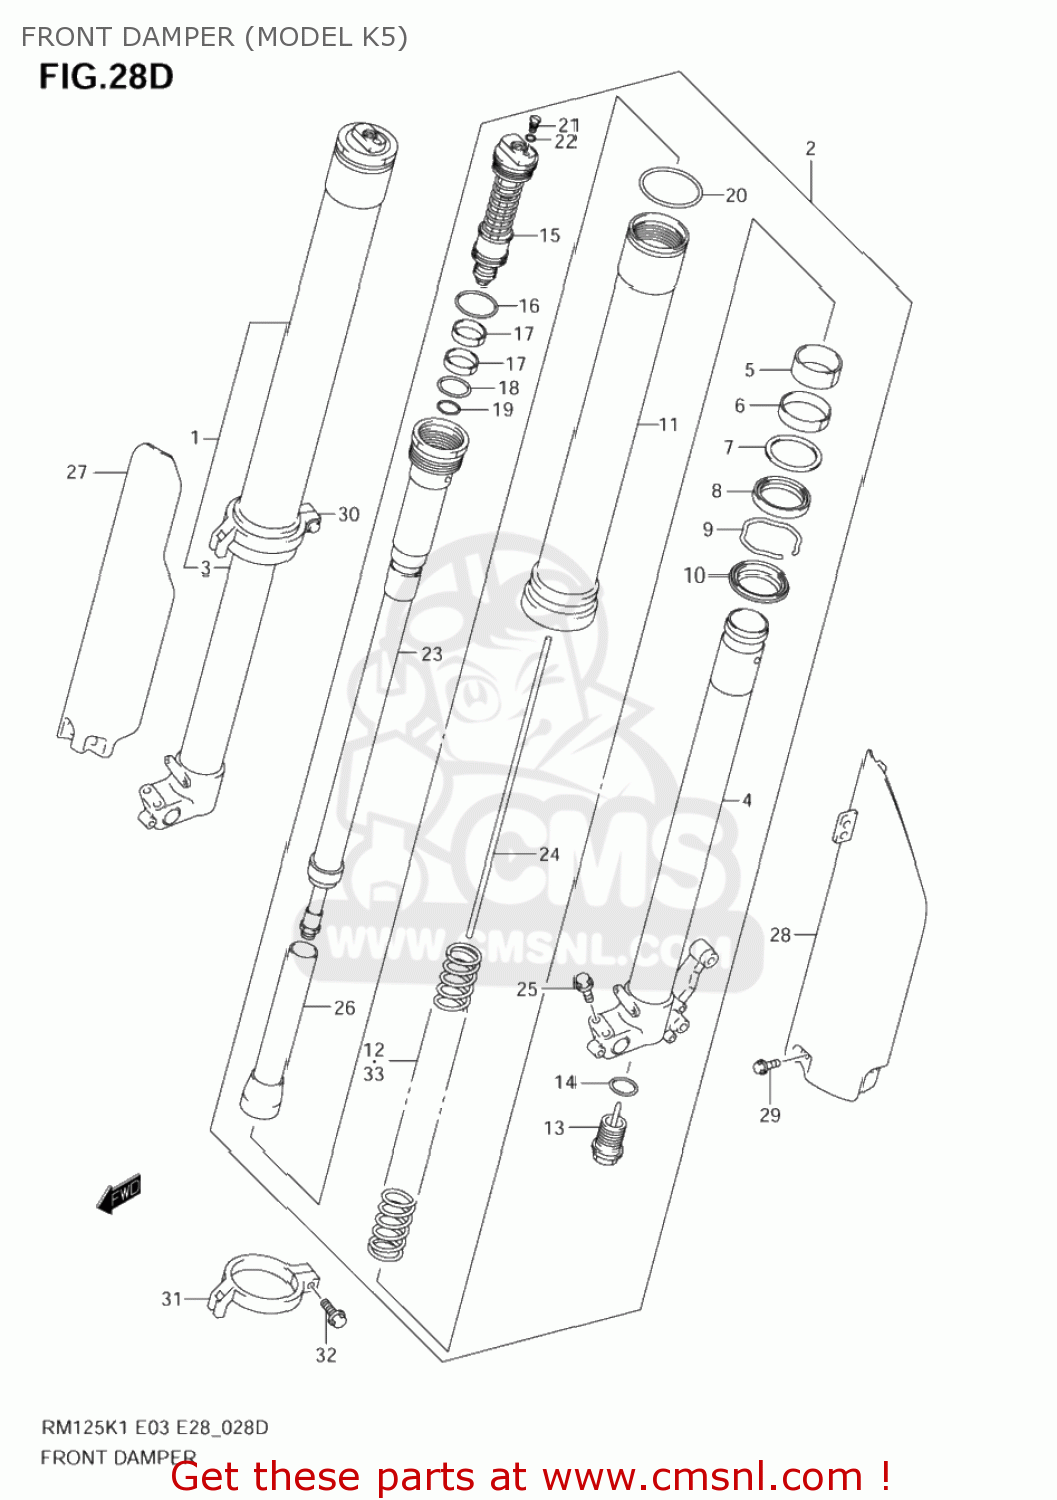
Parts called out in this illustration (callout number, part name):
1	DAMPER ASSY,FR FORK,R
2	DAMPER ASSY,FR FORK,L
3	TUBE,INNER,R
4	TUBE,INNER,L
5	BUSH,SLIDE
6	BUSH,GUIDE
7	SPACER,SEAL
8	SEAL,OIL
9	RING,OIL SEAL STOPPER
10	SEAL,DUST
11	TUBE,OUTER
12	SPRING,FR(SOFT,K=0.42)
13	BOLT,CTR
14	O RING
15	BOLT,FORK
16	O RING
17	BUSH,FORK BOLT SLIDE
18	O RING
19	O RING
20	O RING
21	BOLT,PLUG
22	O RING,PLUG
23	ROD,DAMPER
24	ROD,PUSH
25	BOLT
26	COLLAR,SPRING
27	PROTECTOR,FRON
28	PROTECTOR,FRON
29	BOLT(6X10)
30	GUIDE,PROTECTOR,R
31	GUIDE,PROTECTOR,L
32	BOLT
33	SPRING,FR(K=0.44)
